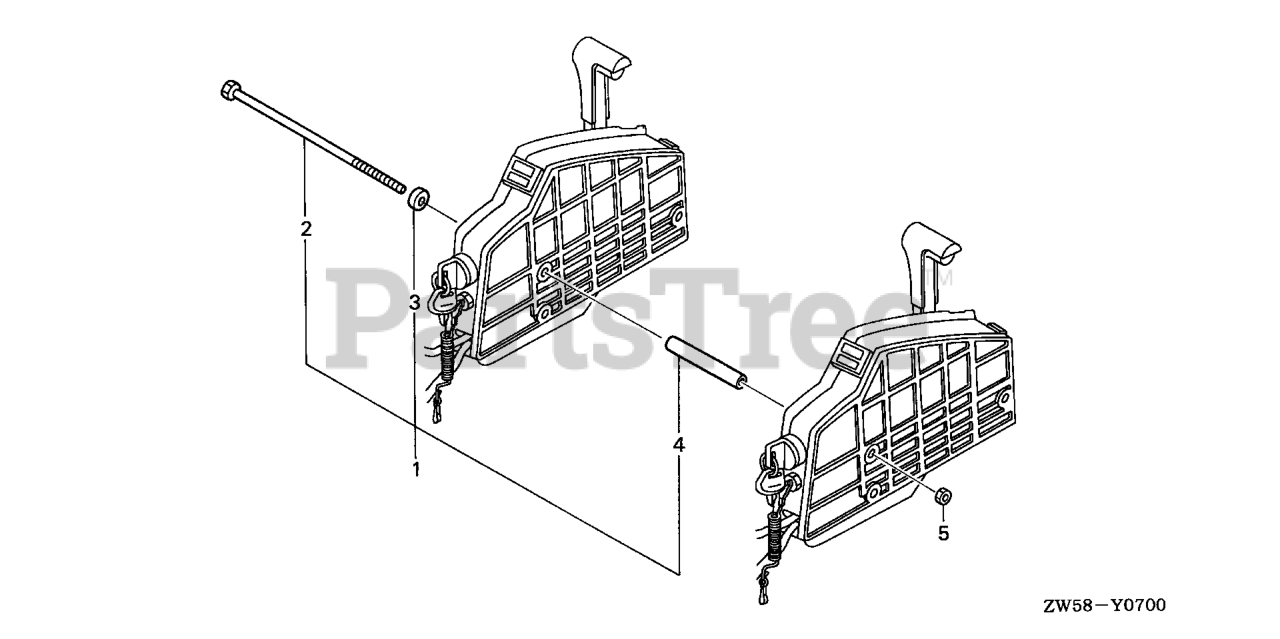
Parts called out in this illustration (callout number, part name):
1	BOLT KIT, SIDE REMOTE CONTROL
2	BOLT, SPECIAL (6X220)
3	COLLAR, DISTANCE (A)
4	COLLAR, DISTANCE (B)
5	NUT, HEX. (6MM)
